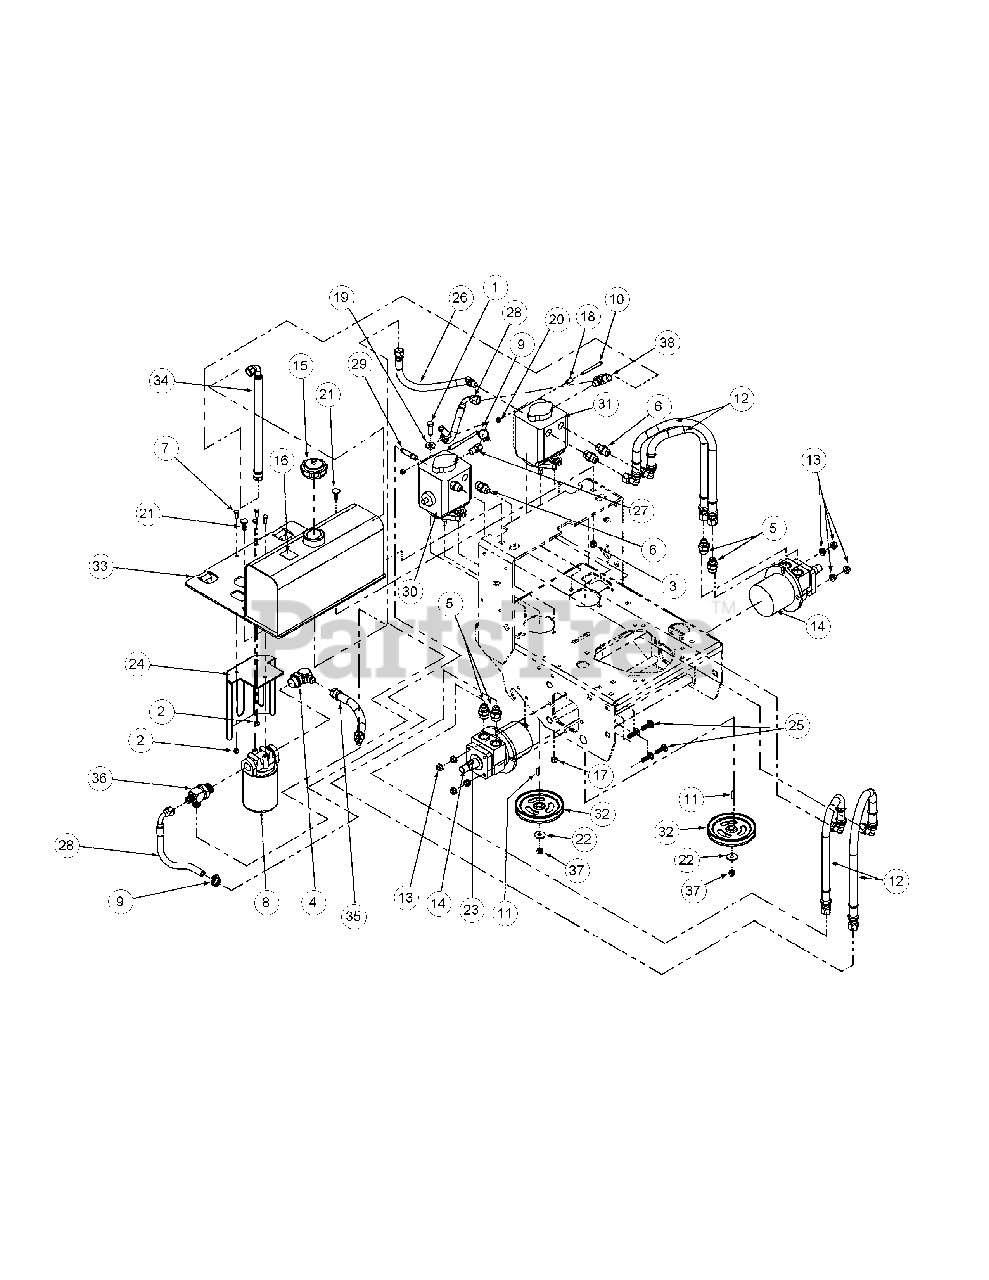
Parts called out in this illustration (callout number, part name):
1	Cap Screw, Standard, 3/8-16 x 1-1/4
2	Lock Nut Nylon Insert, 1/4-20
3	Lock Nut, 3/8-16
4	Elbow 90° 1/2 x 3/4
5	Fitting, Aeroquip
6	Fitting, Aeroquip
7	Cap Screw, 1/4-20 x 3/4
8	Filter Head 3/4 includes:
9	Worm Gear Clamp, 5/16-7/8
10	Cap Screw, Socket Head, 1/4-20 x 1-1/2 Zinc
11	Key, 3/16" x 7/8"
12	Reverse Pressure Hydraulic Hose Assembly
13	Flange Lock Hex Nut, 3/8-16
14	Hydraulic Motor, Wheel
15	Cap, Hydraulic Oil Tank
16	Oil Label, 20W-50
17	Lock Nut, 3/8-16
18	Spacer, Pump Release
19	Washer, Idler
20	Hex Lock Nut, 1/4-20
21	Carriage Bolt, 3/8-16 x 1.0
22	Bell Washer, .396 x 1.140 x .095
23	Woodruff Key, 3/16 x 3/4
24	Filter Guard Weldment
25	Carriage Bolt, 3/8-16 x 1.25
26	Left Pump Inlet Hose
27	Push On Fitting 45
28	Right Pump Inlet Hose
29	Push On Straight Fitting
30	Right Hand, Hydro Pump, BDP 10A 308
31	Left Hand, Hydro Pump, BDP 10A 413
32	Hydro Pump Pulley, 5.00 Dia
33	Fuel Tank Mounting Bracket and Integrated Hydraulic Tank
34	Left Hand, 14.25 Return Hose Assembly
35	9.5" Supply Hose Assembly
36	Tee Fitting, 3/4 x 1/2 x 1/2
37	Hex Nut, 3/8-24
38	Tee Fitting
